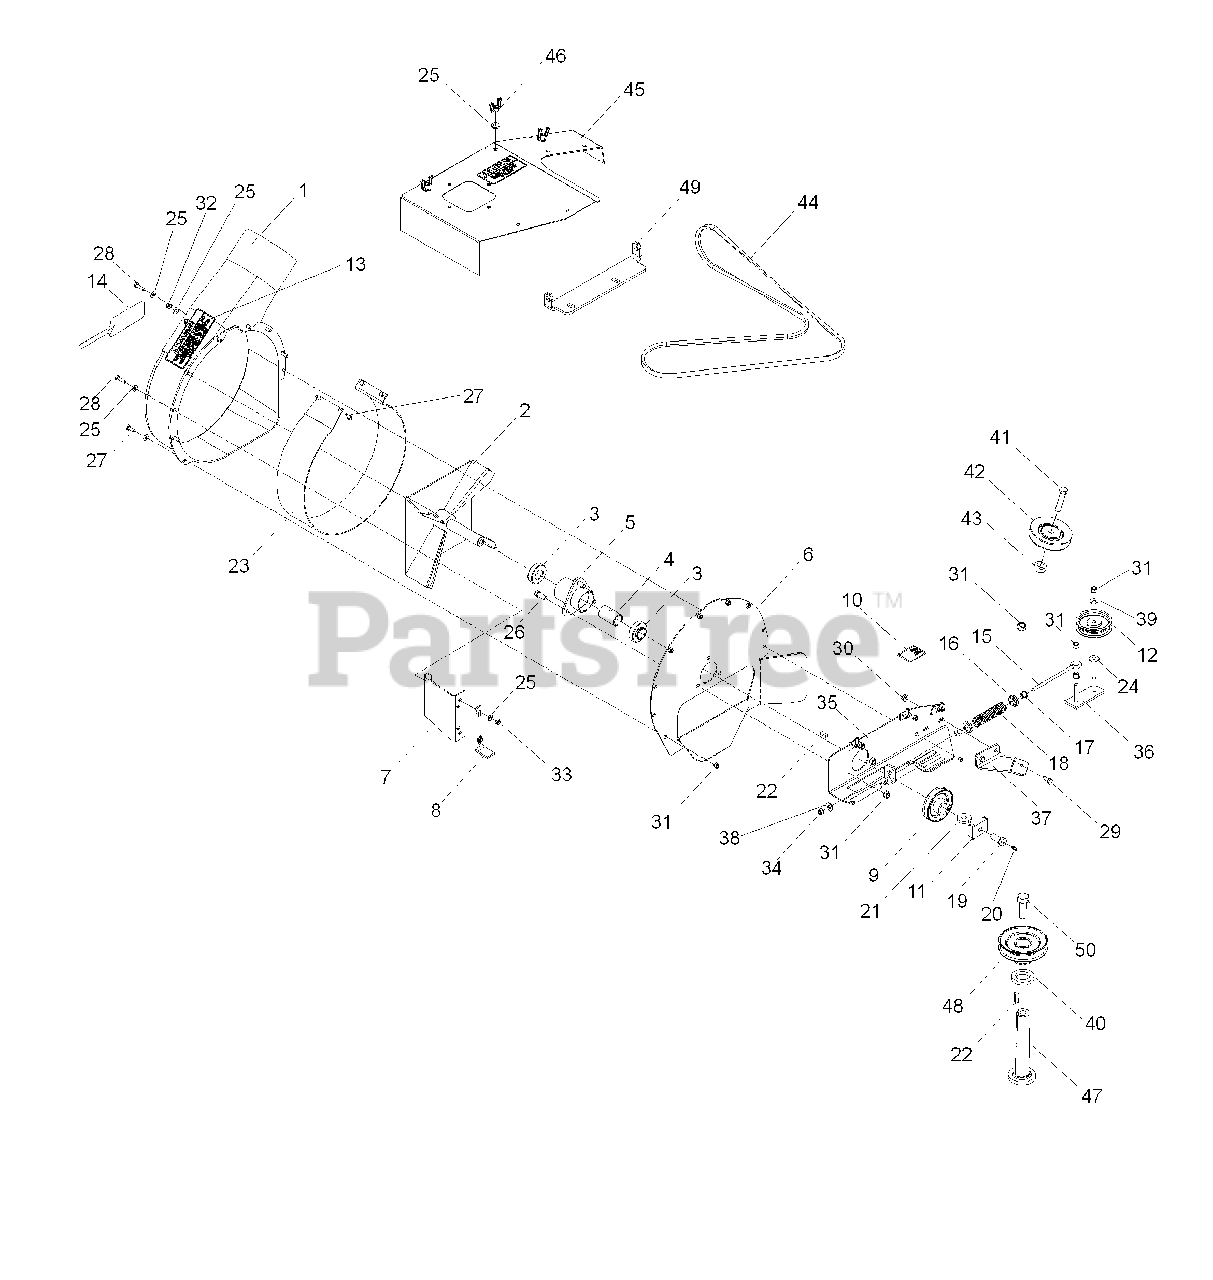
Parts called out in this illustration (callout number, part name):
2	FAN/SHAFT WLDT.
3	BEARING-ECC LOCK
4	SPACER 1 X 2.083
5	HUB WLDT-MACHINED
6	HOUSING PLATE
7	HOUSING GUARD
8	TIP GUARD
9	PULLEY - 3.5
10	DECAL, ROUTING 42"
12	PULLEY, IDLER 3 METAL
13	G.C.WARNING DECAL
14	DECAL, DIXON
15	EYE BOLT 5/16 X 6.00
16	SPRING RETAINER
17	FLIP-LOK BUSHING
19	HUB BOLT-DRILLED
20	ZERK, 3/16, DRIVE IN
21	WASHER .525 X 1.375 X .25
22	OUTER SHAFT KEY
23	SAND LINER
24	WASHER 3/8 FLAT
25	1/4` SAE FLAT WASHER
26	HCS 3/8C X 1
27	HCS 1/4C X 3/4 HCS
28	HCS 1/4C X 1
29	HCS 5/16C X 3/4
30	5/16-18 FLANGED L-NUT
31	NUT 3/8-16 NYLOC
32	NUT 1/4-20 NYLOC
33	JAM NUT 1/4C
34	NUT 5/16 NYLOC
35	IDLER BASE WLDT.
36	SLIDE ARM WLDT
37	IDLER MOUNT BRACKET
38	WASHER 5/16 FLAT
39	WASHER 3/8 SAE FLAT
40	SPACER .25
41	HCS 3/8-16 X 1 3/4 GR5
42	PULLEY, IDLER 3 METAL
43	BLADE ADAPTOR
44	V BELT - BLOWER
45	50` GUARD ASM
46	WING NUT 1/4
47	SHAFT LONG
48	PULLEY METRIC(BLOWER)
49	BRACKET, MOUNT, BLOWER
50	1/2-20X1-1/2 HHB G5
